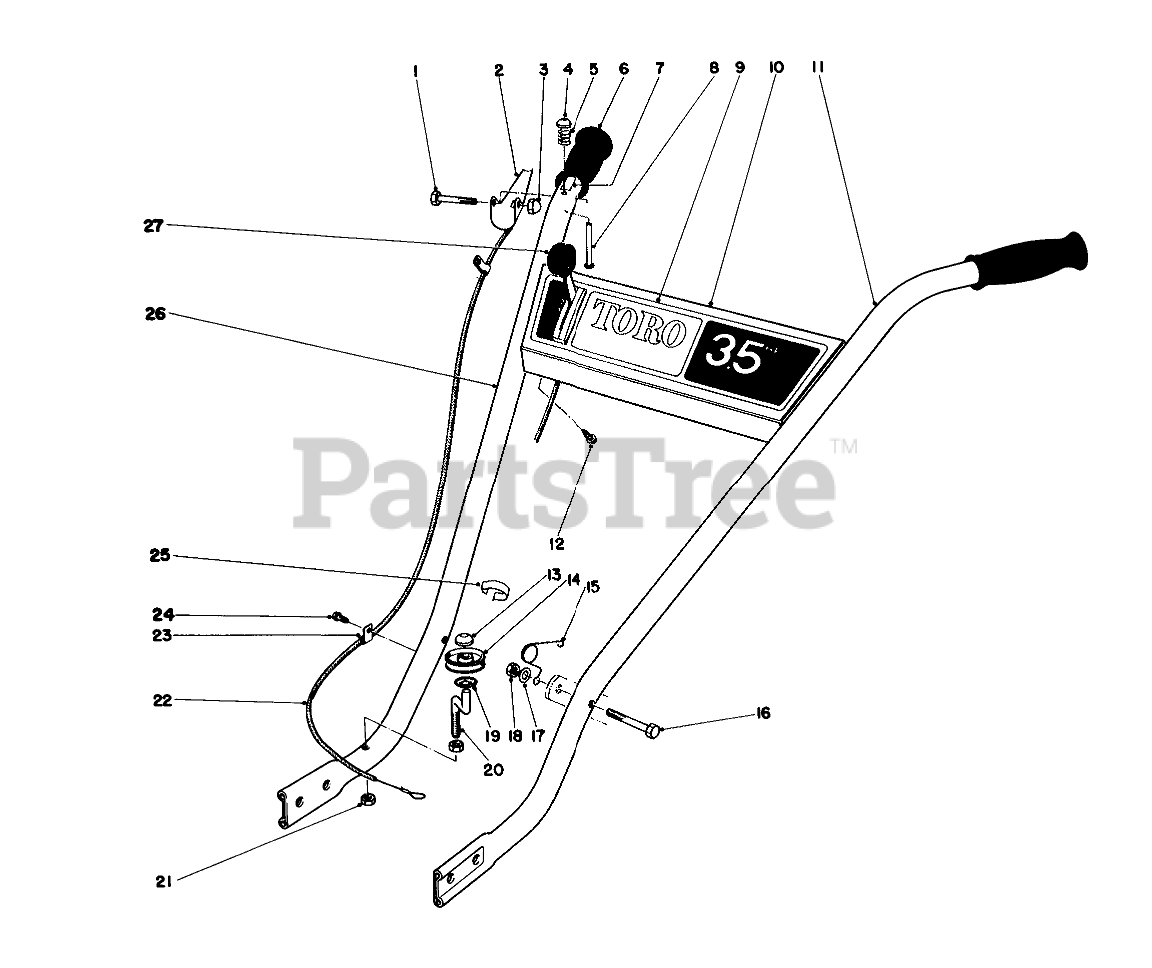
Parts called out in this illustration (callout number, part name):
1	SCREW-HH
2	LIFTBAIL
3	NUT-CAP
4	Push-On
5	COMPRESSION SPRING
6	Hand Grip
7	Decal-Fwd.
8	LOCK PIN
9	Decal-Escutcheon
10	Escutcheon Panel
11	L.H. Handle
12	SCREW-HWHTF
13	RETAINER PUSH ON
14	Pulley Cable
15	Spring-Torsion
16	SCREW-HH
17	WASHER-PLAIN
18	NUT-LOCK, CONE
19	PUSH ON RETAINER
20	Spindle-Fwd.
21	LOCKNUT
22	FWD CABLE ASM
23	3/16 SUPPORT
24	10 X 1/2 SCREW
25	Boden Clip
26	RH HANDLE
27	Throttle Control
